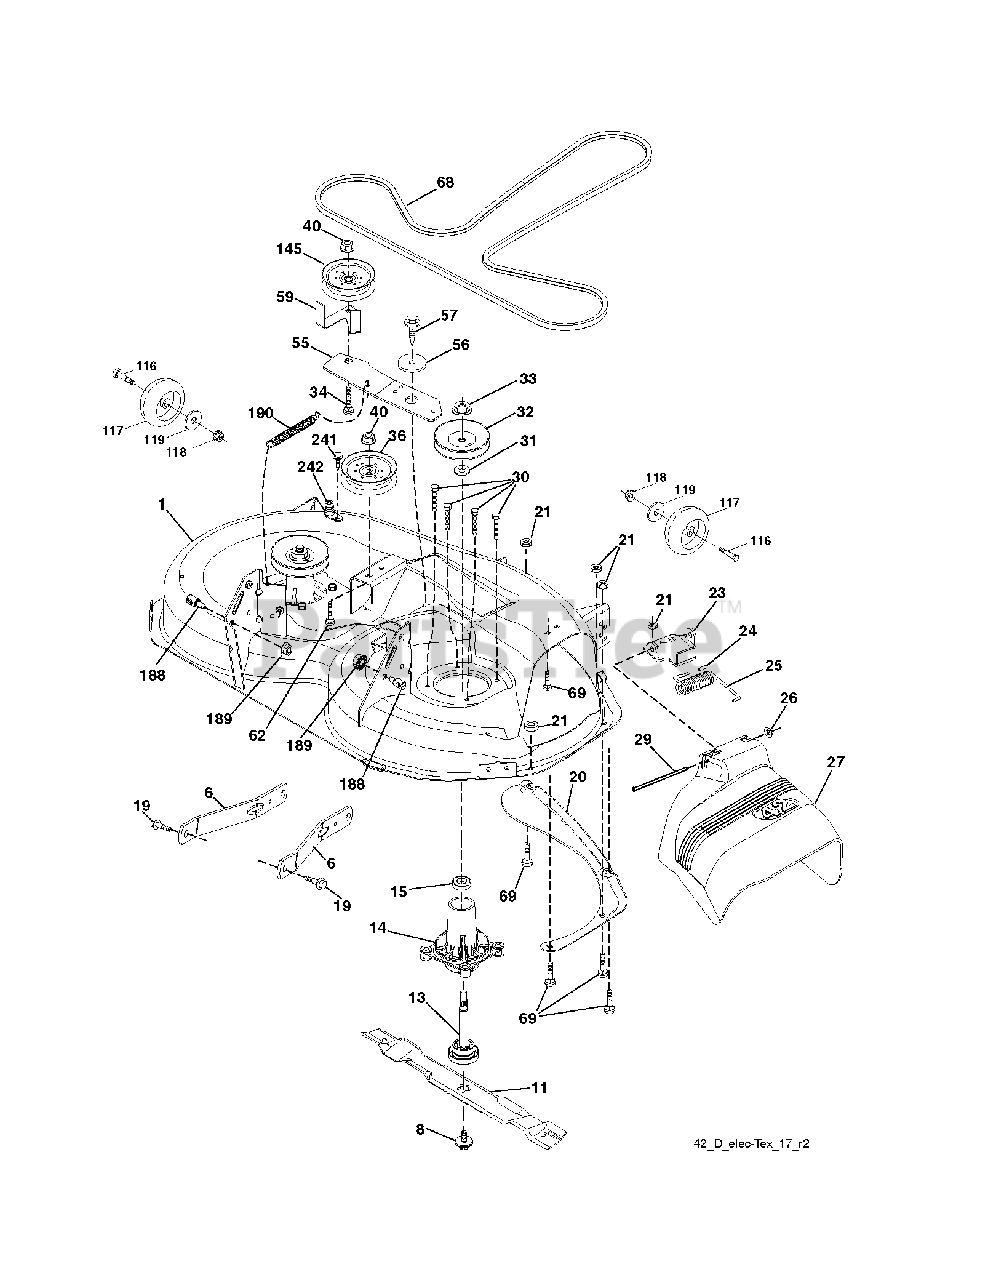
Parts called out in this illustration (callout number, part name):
1	DECK.WELDMNT.42"GREYMS498
6	ARM.SUSPENSION.MOWER.R
8	BOLT.WASHER.ASM.7/16-2
11	42" HI-LIFT BLADE
13	SHAFT.ASM.MDRL.N/GREASE.38
14	HOUSING.MANDREL.4PT.
19	BOLT.SHOULDER
20	BAFFLE.VORTEX
21	LOCKNUT
23	BRKT.DEFLECTOR.38"2005+
24	CAP-SLEEVE LT
25	SPRING.TORSION.DEFLECT
26	NUT PUSH M
27	SHIELD.DEFLECTOR.MOWER.42"BLAC
29	ROD.HINGE
30	SCREW, WASHER HEAD
31	WASHER.SPACER.MANDREL
32	PULLEY/MANDREL
33	NUT.FLANGE.LOCK.TOP
34	BOLT.3/8-16X1.50
36	PULLEY.IDLER.2006
40	NUT LOCK FLG 3/8-16 UNC
55	IDLER.ARM.42"
56	SPACER.RETAINER
57	SCREW 3/8-16X1
59	GUARD, BELT
68	BELT V SECONDARY
69	BOLT
116	BOLT M
117	WHEEL.GAGE.HALF.SPOKED
118	LOCKNUT
119	WASHER
145	PULLEY.IDLER.48"PRIMARY
188	STUD.FASTNER.W/ANTI-ROTATE
189	NUT LOCK HEX FLANGE 5/16-18
190	SPRING.MOWER.DRIVE.ELECTRIC
241	SCREW.TT.#10-32X.5.3/8.FLANGE
242	PORT.WASHOUT
